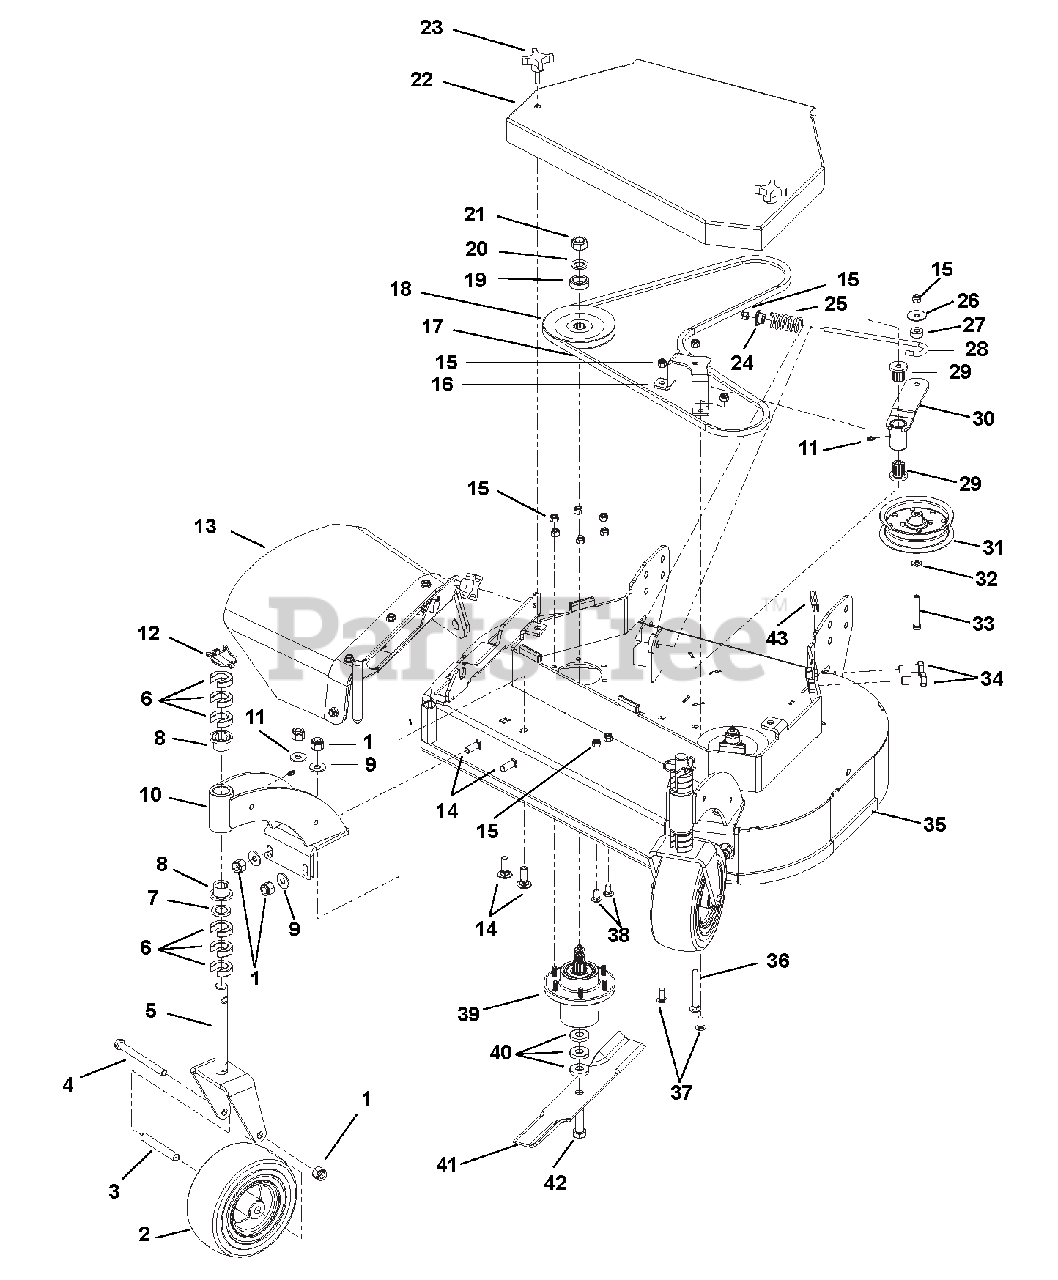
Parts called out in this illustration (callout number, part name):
1	LOCKNUT, 1/2-13 NYLOC Y
2	ASSY, WHEEL AND TIRE 9X3.5
3	TUBE, CASTER AXLE
4	@BLT-HEX .50-13X5.50 GR5YWZC
5	WLDT, CASTER YOKE ARIENS
6	C-SPACER, 1.00 X 1.77 X .500
7	BUSHING, 1.03 X 1.50 X .179 Y
8	BRG, FLG 1.00X1.25X1.00
9	MANUAL, OWNERS RAPID XZ FRENCH
10	WLDT, STRUT FRONT WHEEL ARIENS
11	FTG, 1/4-28 STRGT GREASE ZERK
12	PIN, KLIK .438X2.00
13	ASSY, DISCHARGE SHIELD ARIENS
14	@BLT-RDHDSQNK .50-13X1.50 G5YZ
15	LOCKNUT, 3/8-16 NYLOC Y
16	BRACKET, IDLER
17	BELT, HB 80.3 EL AMD OHR
18	PULLEY, NARROW SPLINE
19	SPACER, SPINDLE TOP-PULLEY
20	WASHER, .75X1.3125X.120
21	LOCKNUT, 3/4-16 CROWN GR 8 Y
22	WLDT, BELT SHIELD 36"GRWLK ARI
23	KNOB, 3/8 X 1.25 - 4 PRONG
24	KEEPER, SPRING
25	SPRING, COM 1.22X.162X2.50 Y
26	WASHER, .375X1.50X.063 FLAT Y
27	BUSHING, .380 X 1.00 X .410 Y
28	J-BOLT, 3/8-16 X 7.88 Y
29	BRG, FLG M10XM25XM27 FLUTED
30	WLDT, IDLER ARM WITH OFFSET
31	PULLEY, FLAT 5.00X.375 W/BRG
32	WASHER, .406X.813X.065 FLAT Y
33	@BLT-HEX .38-16X2.75 GR5 YWZC
34	BOLT, HEX 5/8-11 1.5" GR8 YWZC
35	ASSY, 36" DECK W/DECALS ARIENS
36	BOLT, 3/8-16X3.50 CRG 5 Y
37	BOLT, 3/8-16X1.00 CRG 5 SN Y
38	@BLT-RHDSSQNK .38-16X.75 G5YZ
39	ASSY, SPINDLE S/O
40	WASHER, .630X1.50X.250 FLAT Y
41	BLADE, 18.000 X .80 LIFT
42	BOLT, 5/8-11 X 2.00 HEX 8 Y
43	TRIM, LOCK 1/4" EDGE
